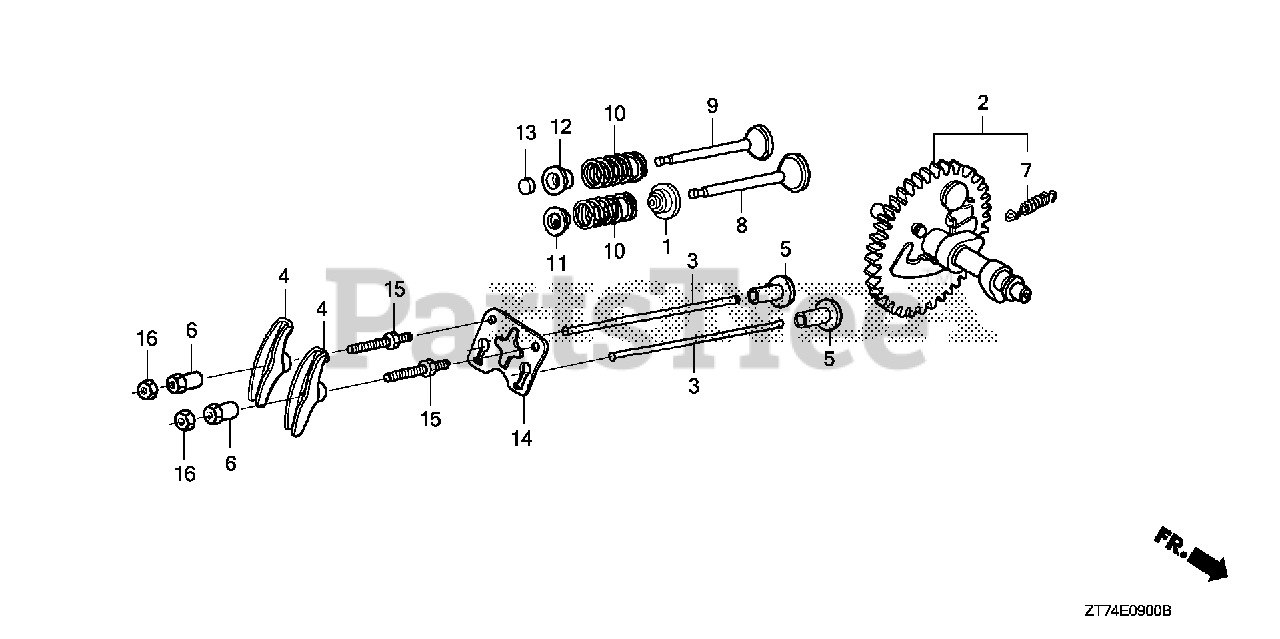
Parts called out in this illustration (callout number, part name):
1	SEAL, VALVE STEM
2	CAMSHAFT ASSY.
3	ROD, PUSH
4	ARM, VALVE ROCKER
5	LIFTER, VALVE
6	PIVOT, ROCKER ARM
7	SPRING, WEIGHT RETURN
8	VALVE, IN.
9	VALVE, EX.
10	SPRING, VALVE
11	RETAINER, VALVE SPRING (EXHAUST SIDE)
12	RETAINER, VALVE SPRING (EXHAUST SIDE)
14	PLATE, PUSH ROD GUIDE
15	BOLT, PIVOT (8MM)
16	NUT, PIVOT ADJ.
